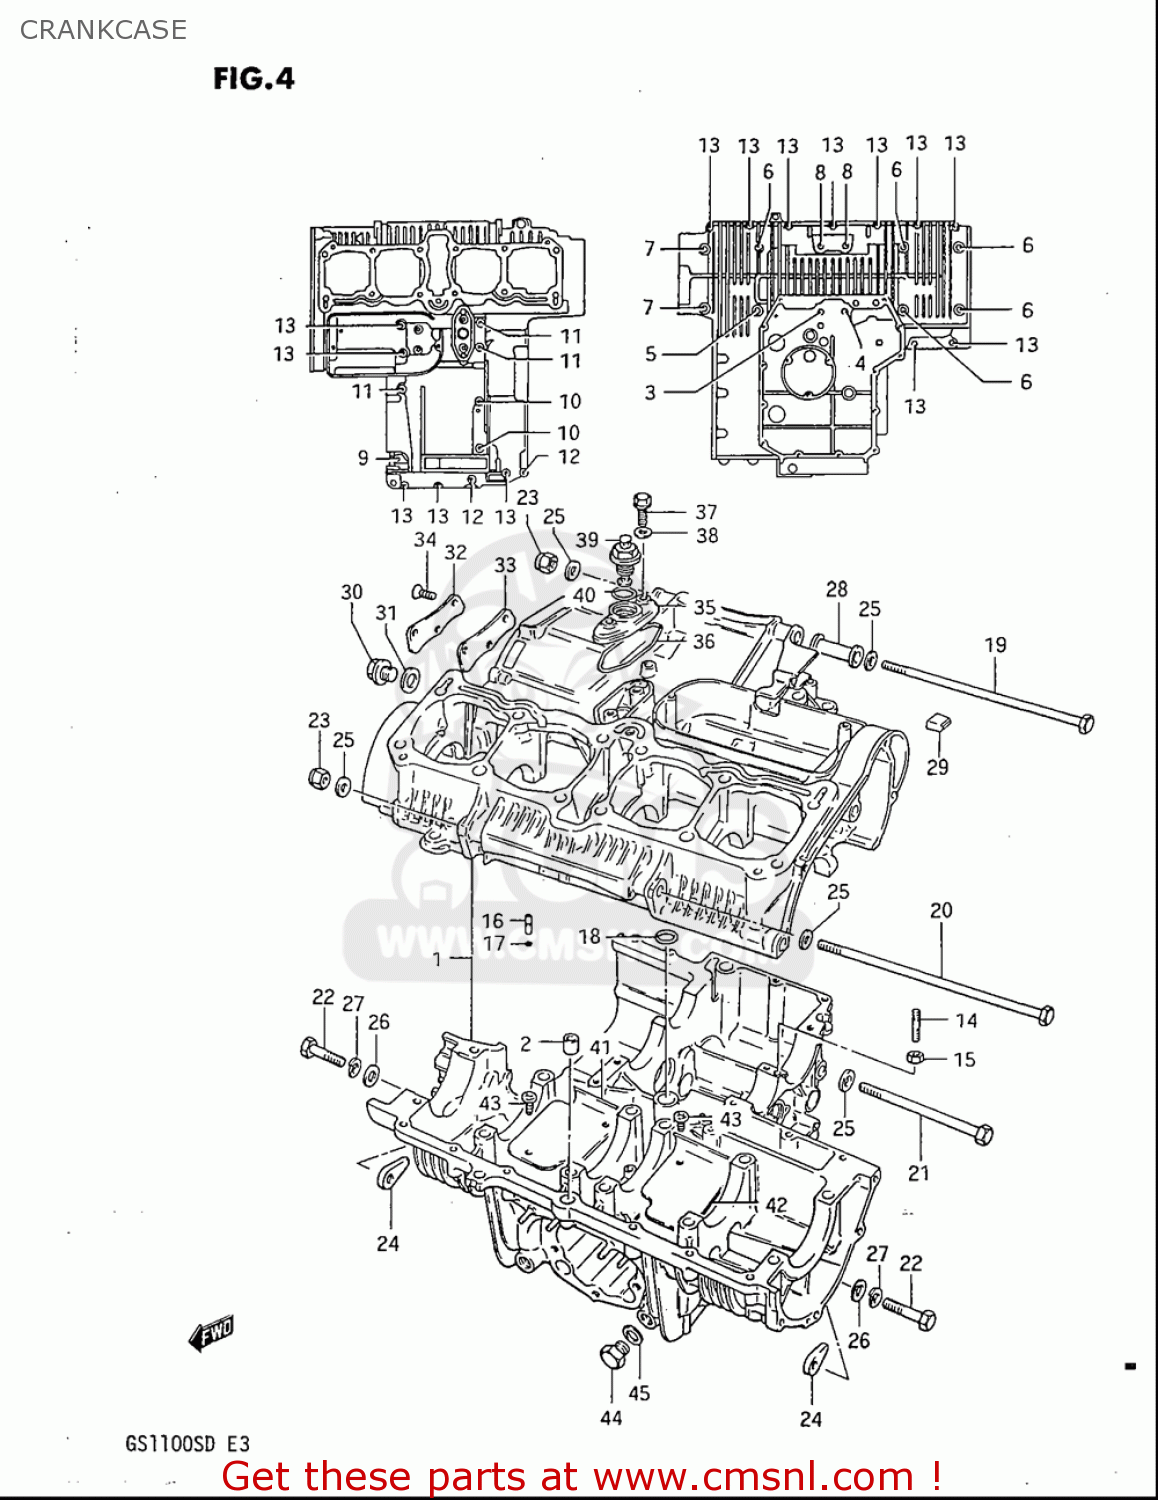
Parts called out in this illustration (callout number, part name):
1	CRANKCASE SET
2	PIN
3	BOLT 8X155
4	BOLT(8X125)
5	BOLT(8X100)
6	BOLT
7	BOLT
8	BOLT
9	BOLT
10	BOLT
11	BOLT
12	BOLT, HYDRAULIC UNIT NO.2
13	BOLT
14	STUD BOLT
15	NUT
16	UNION
17	O RING(D:1.05,ID:3.1)
18	O RING(D:3.2,ID:12.9)
19	BOLT(10X225)
20	BOLT(10X250)
21	BOLT(10X165)
22	BOLT 10X60
23	NUT (10MM)
24	NUT
25	WASHER
26	WASHER(10.5X20X3.2)
27	WASHER,LOCK
28	SPACER
29	PAD,CYLINDER
30	PLUG(14X12)
31	GASKET(14X19.2X2) (NAS)
32	CAP,OIL GALLERY
33	GASKET,OIL GALLERY CAP (NAS)
34	SCREW
35	HOUSING,OIL PRESSURE SWITCH
36	O RING,PRESSURE SWITCH HOUSING
37	BOLT
38	GASKET(5.8X13X1.2) (NAS)
39	SWITCH ASSY,OIL PRESSURE
40	O RING(D:1.9,ID:18.8)
41	PLATE,OIL SEPARATOR
42	PLATE,OIL SEPARATOR
43	SCREW
44	PLUG
45	GASKET(14X19.2X2) (NAS)
